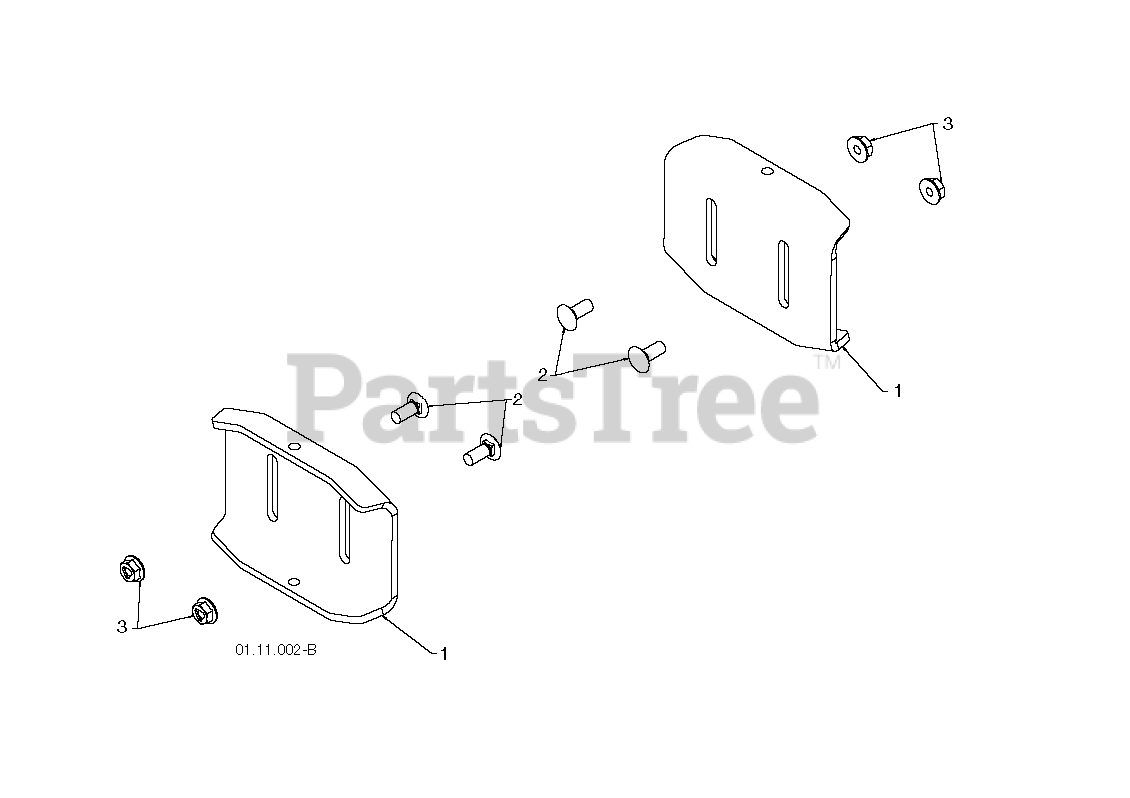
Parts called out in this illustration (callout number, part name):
1	PLATE.SKID.HEAVYDUTY.BLACK
2	BOLT
3	NUT.LOCK.5/16-18
